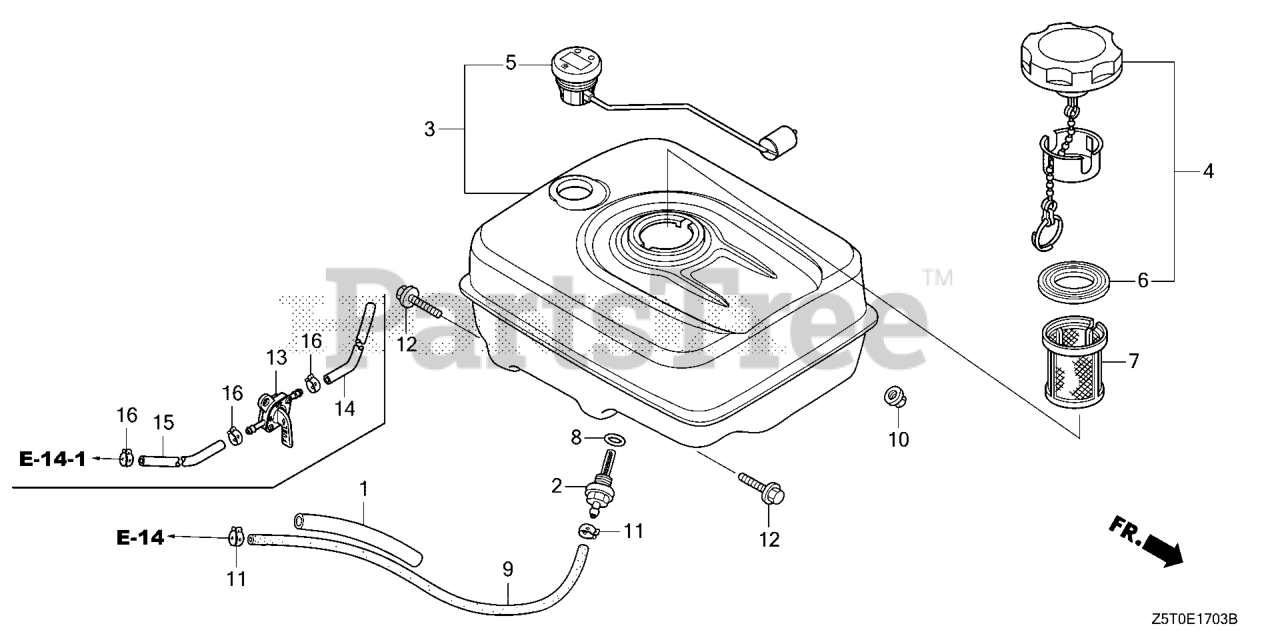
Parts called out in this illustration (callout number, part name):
1	RUBBER, SUPPORTER (107MM)
2	JOINT, FUEL TANK
3	TANK ASSY., FUEL *NH31* (GAUGE) (MCKINLEY WHITE)
4	CAP, FUEL FILLER
5	GAUGE ASSY., FUEL
6	GASKET, FUEL FILLER CAP
7	FILTER, FUEL (FROM 1204807)
8	O-RING (14MM) (ARAI) Use up to Engine SN 2949254.
9	TUBE, FUEL (4.5X235) (FKM)
10	NUT, FLANGE (8MM)
11	CLIP, TUBE (D8)
12	BOLT, FLANGE (8X25)
